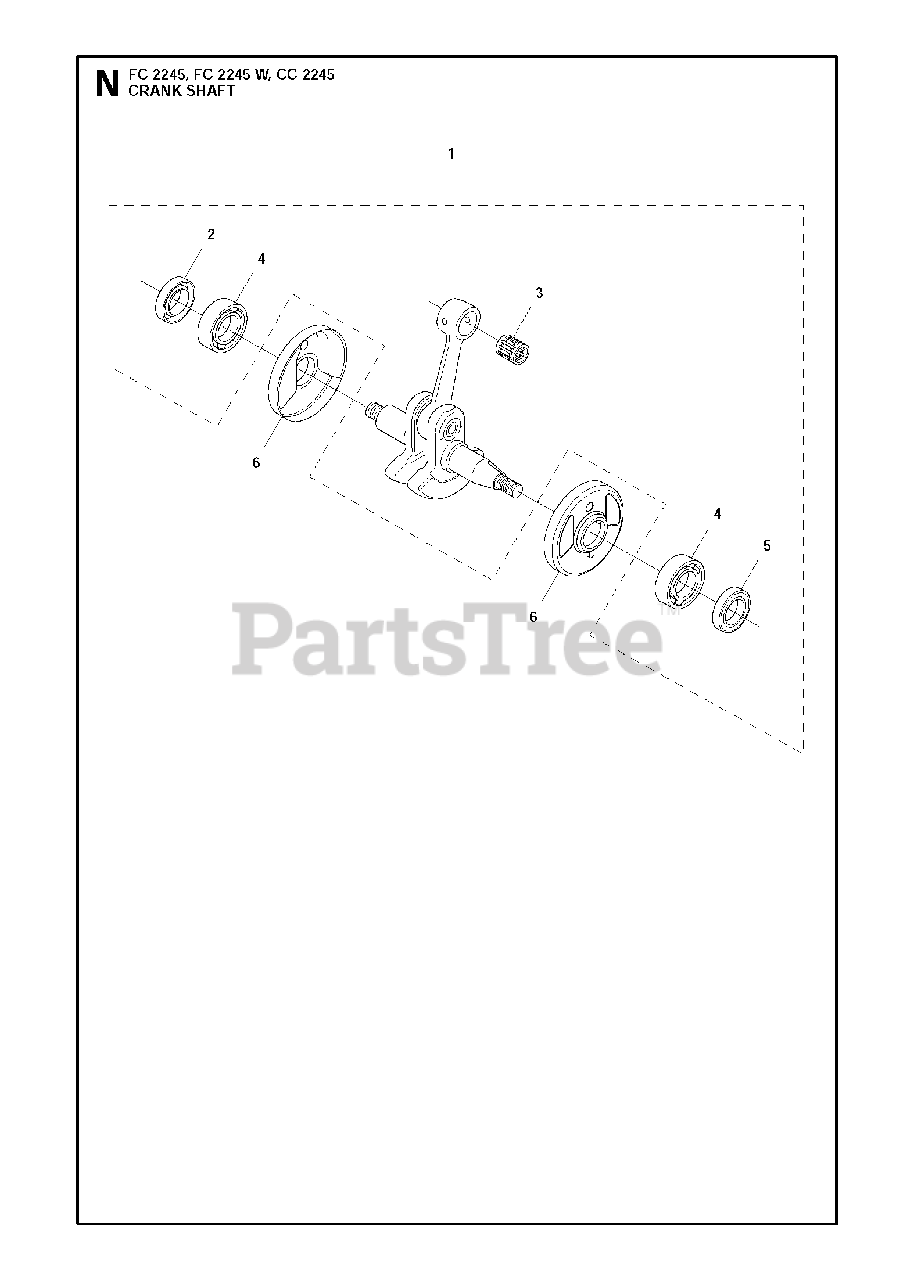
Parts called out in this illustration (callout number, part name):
1	CRANKSHAFT
2	RADIAL SEAL
3	NEEDLE BEARING
4	BALL BEARING
5	SEAL RING
